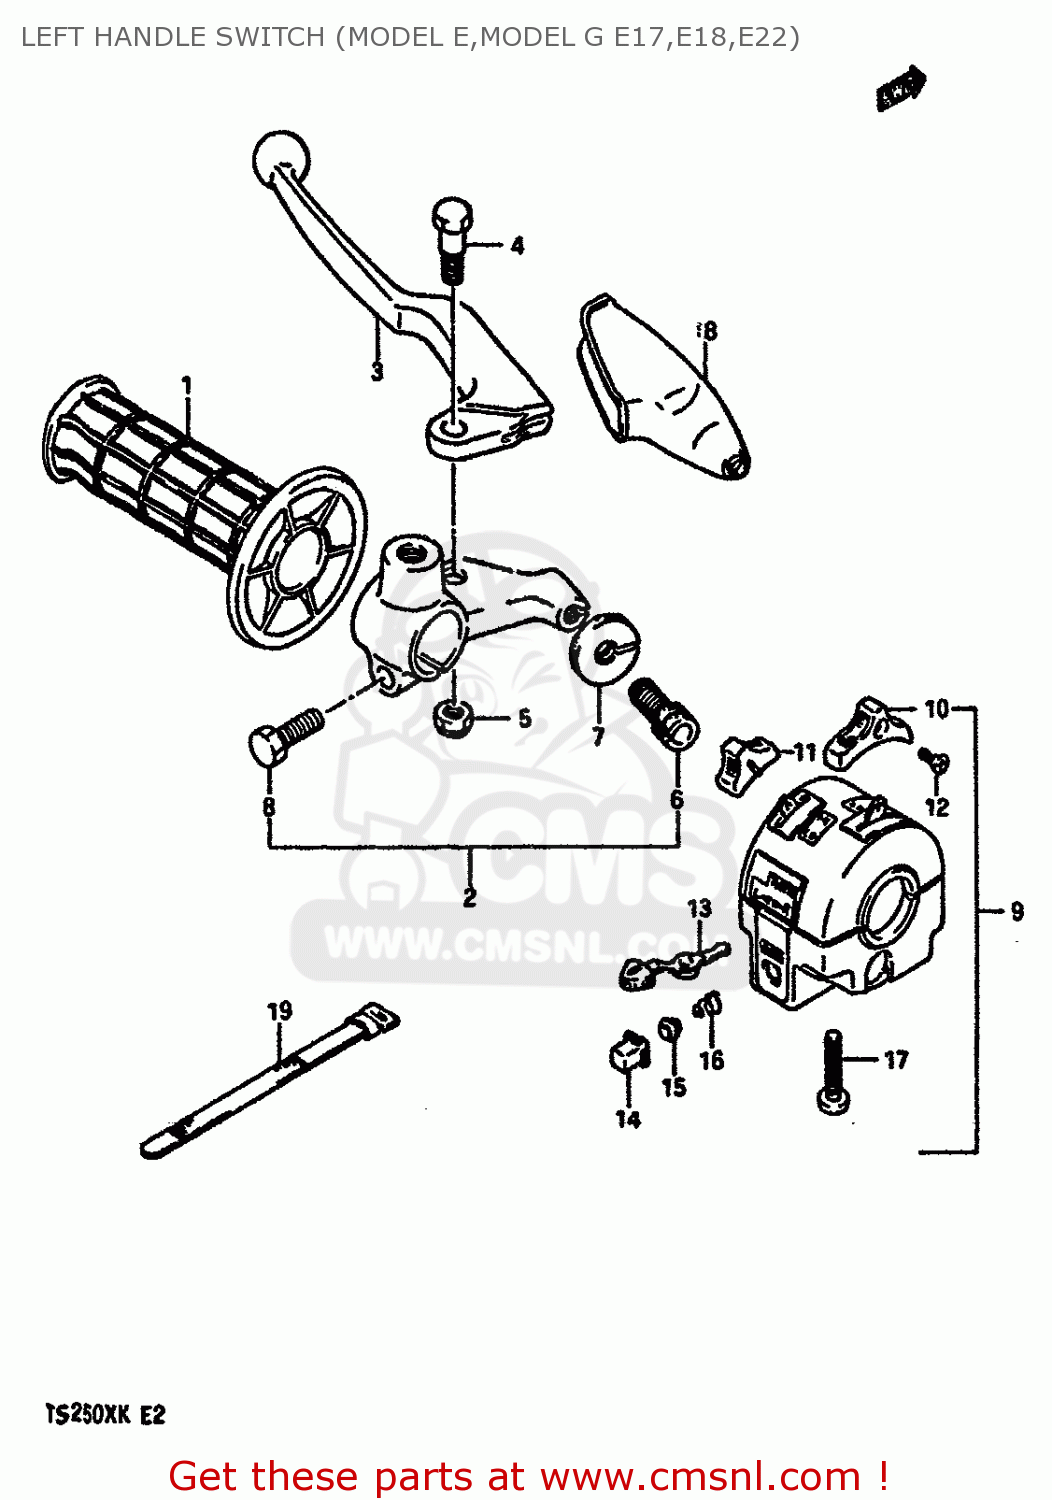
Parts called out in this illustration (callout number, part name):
1	GRIP,LEFT
2	LEVER ASSY, CLUTCH
3	LEVER,CLUTCH
4	BOLT,LEVER
5	NUT
6	ADJUSTER,CABLE
7	NUT,CABLE ADJUSTER LOCK
8	BOLT
9	SWITCH ASSY,HANDLE LH
10	KNOB,LIGHTING SWITCH
11	KNOB,DIMMER SWITCH
12	SCREW
13	KNOB,TURNSIGNAL
14	BUTTON,HORN
15	CONTACT
16	SPRING
17	SCREW
18	COVER,CLUTCH LEVER
19	CLAMP(L:120)
